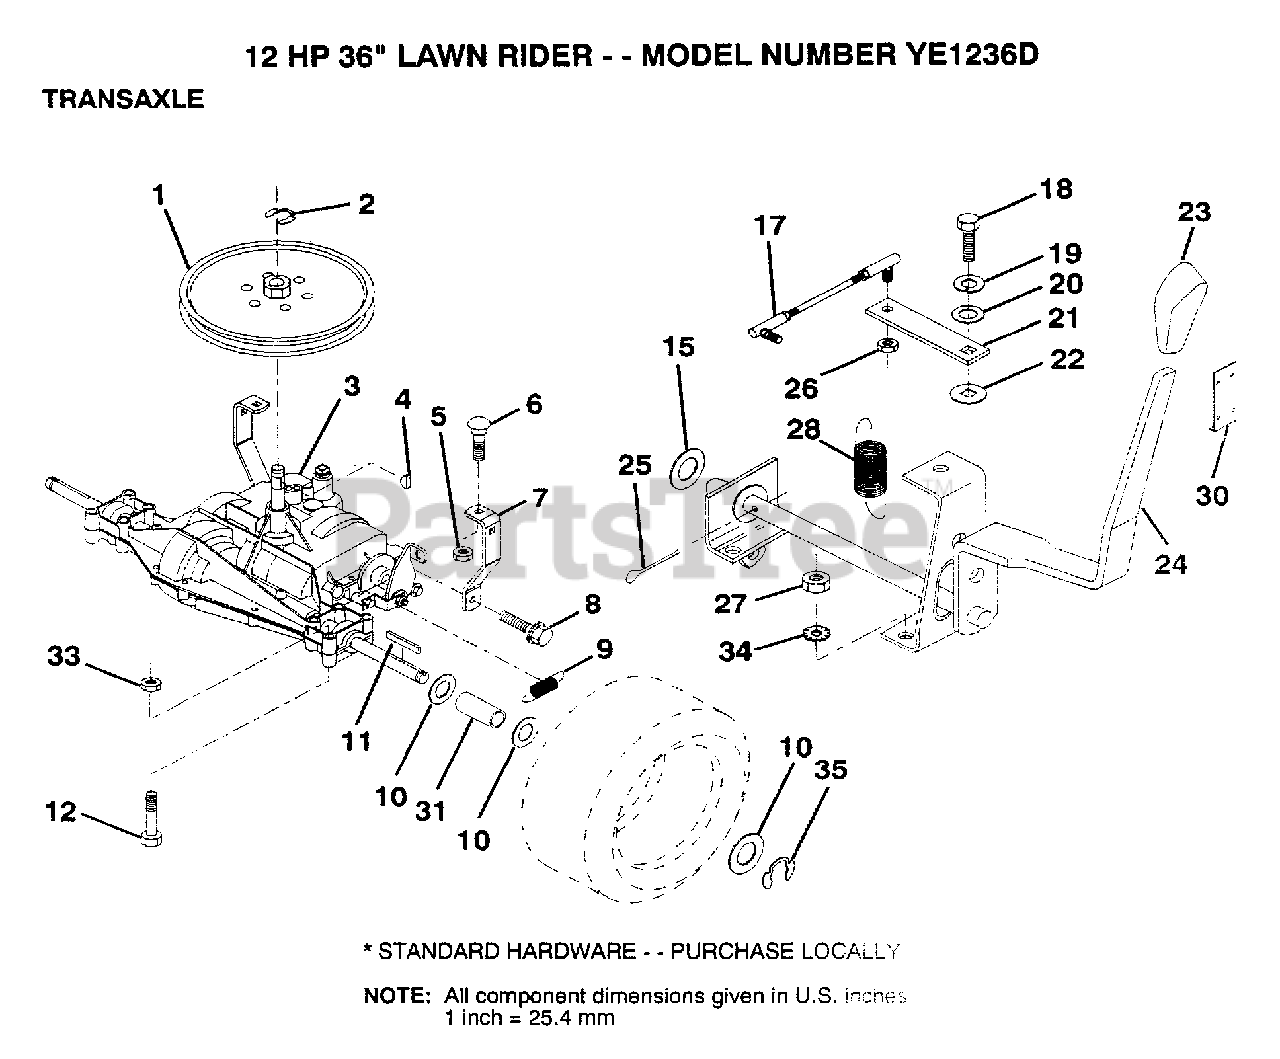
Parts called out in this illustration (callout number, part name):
1	PULLEY
6	BOLT
7	"STRAP,TORQUE"
8	SCREW
10	WASHER
11	SQUARE KEY
12	BOLT
17	"LINK,SHIFT"
19	LOCKWASHER
20	WASHER LT
21	"ARM,SHIFT"
22	WASH-SHFT PLT LT
23	"KNOB,SHT CONTROL"
25	PIN COTTER 1/8
26	NUT.LOCK.5/16-24
28	"SPRING,EXT"
30	KNOB RETAINER
31	SPACER
34	LOCKWASHER.5/16.E
35	E-RING LT
